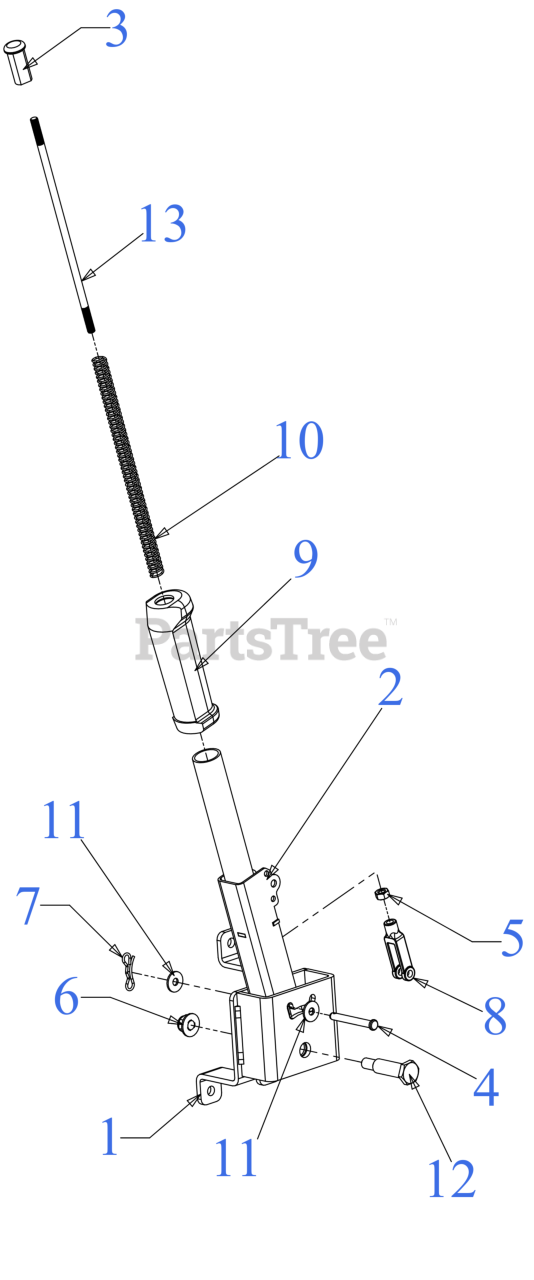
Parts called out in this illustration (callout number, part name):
1	HANDLE BRACKET
2	DISCHARGE HANDLE
3	LIFT HANDLE BUTTON
4	CLEVIS PIN 0.25 x 2.00
5	HEX NUT 1/4-28
7	BOW TIE COTTER PIN 1/4-5/16
8	DIFF LOCK ACTUATOR YOKE
9	LIFT HANDLE GRIP
10	COMPRESSION SPRING
11	FLAT WASHER
12	SHOULDER SCREW .498 DIA x 1.450-THD
13	HANDLE ROD
